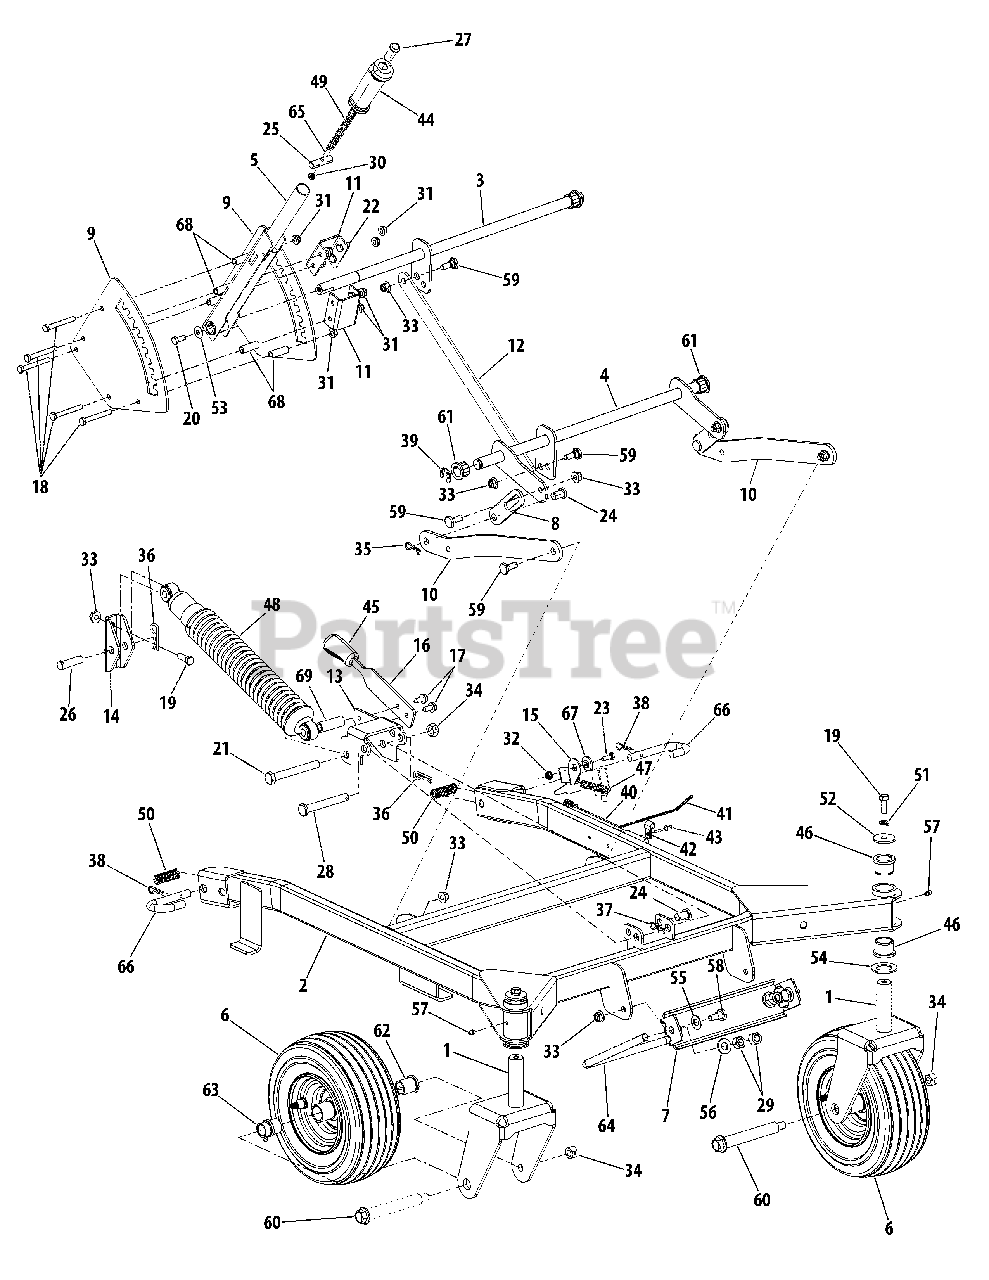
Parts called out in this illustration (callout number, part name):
2	Frame, Deck
18	Screw, Hex Cap, 5/16-18 x 2.5 Gr5
19	Screw, Hex Cap, 3/8-16 x 1.0 Gr5
20	Screw, Hex Cap Lock, 5/16-24 x .75 Gr5
21	Screw, Hex Cap, 1/2-13 x 4.0 Gr5
22	Screw, Hex Cap, 5/16-18 x .75 Gr5
23	Screw, Hex Cap, 1/4-20 x .75 Gr5
24	Pin, Clevis, .5 x .78
25	Pin, Index
26	Pin, Clevis, .5 x 1.59
27	Button, Handle
28	Pin, Clevis, .5 x 3.75
29	Nut, Hex, 1/2-13 Gr5
30	Nut, Hex Jam, 1/4-20
31	Nut, Hex Insert Flange Lock, 5/16-18 GrF
32	Nut, Hex Insert Flange Lock, 1/4-20 GrF
33	Nut, Hex Insert Flange Lock, 3/8-16 GrF
34	Nut, Hex Lock, 1/2-13 GrB
35	Pin, Internal Cotter
36	Pin, Internal Cotter
37	Pin, Internal Cotter
38	Pin, Internal Cotter
39	E-Ring, Retainer
40	Harness, Safety
41	Tie, Cable, Push Mount
42	Clamp, Hose
43	Rivet, Pop, .188 x .3
44	Grip, Deck Lift Handle
45	Grip, Shock Absorber Handle
46	Bearing, Flange, 1.0 x 1.246
47	Spring, Extension, .50 x 4.35
48	Shock Absorber
49	Spring, Compression, .4 x 8.52
50	Spring, Compression, .66 x 1.9
51	Washer, Lock, 3/8
52	Washer, Flat, .39 x 1.5 x .134
53	Washer, Belleville, .34 x .872 x .06
54	Washer, Flat, 1.0 x 1.75 x .107
55	Washer, Flat, .52 x 1.0 x .06
56	Washer, Flat, .531 x 1.062 x .134 HT
57	Fitting, Lube, 3/16 Drive
58	Screw, Shoulder, .496 x .336: 3/8-16
59	Screw, Shoulder, .5 x .27:3/8-16
60	Bolt, Shoulder, .75 x 4.75: 1/2-13
61	Bearing, Hex Flange, .75 ID
62	Bearing, Flange, .76 x 1.0 x 1.2
63	Bearing, Flange, .76 ID w/ Lube Fitting
64	Rod, Deck Front Hanger
65	Rod, Lift Index
66	Rod, Deck Release
67	Spacer, Shoulder, .5 x .11 x .25
68	Spacer, Handle
69	Spacer, .51 x .69 x 1.97
